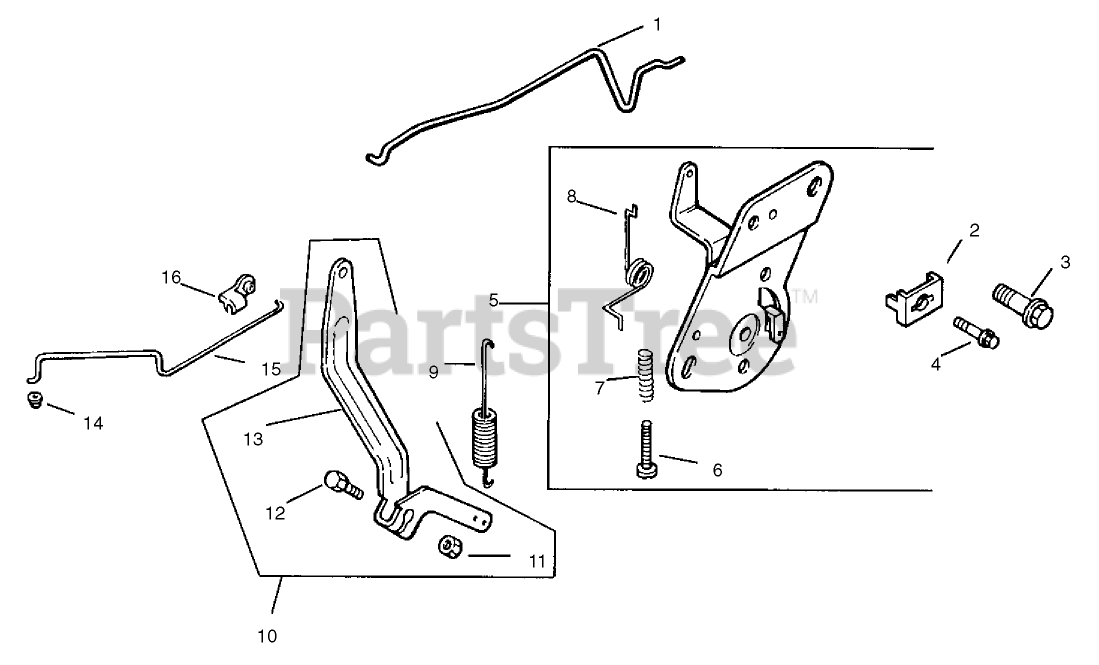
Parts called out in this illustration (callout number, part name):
1	Linkage Choke
2	Clamp
3	Screw Socket
4	Screw
5	Control-Speed
6	Screw
7	Spring
8	Spring Choke
9	Spring-Governor
10	Kit-Governor Lever (Incl. Ref.#11-13)
11	Nut
12	Bolt
13	Lever-Governor
14	Bushing-Linkage
15	Linkage-Throttle
16	Bushing-Linkage
